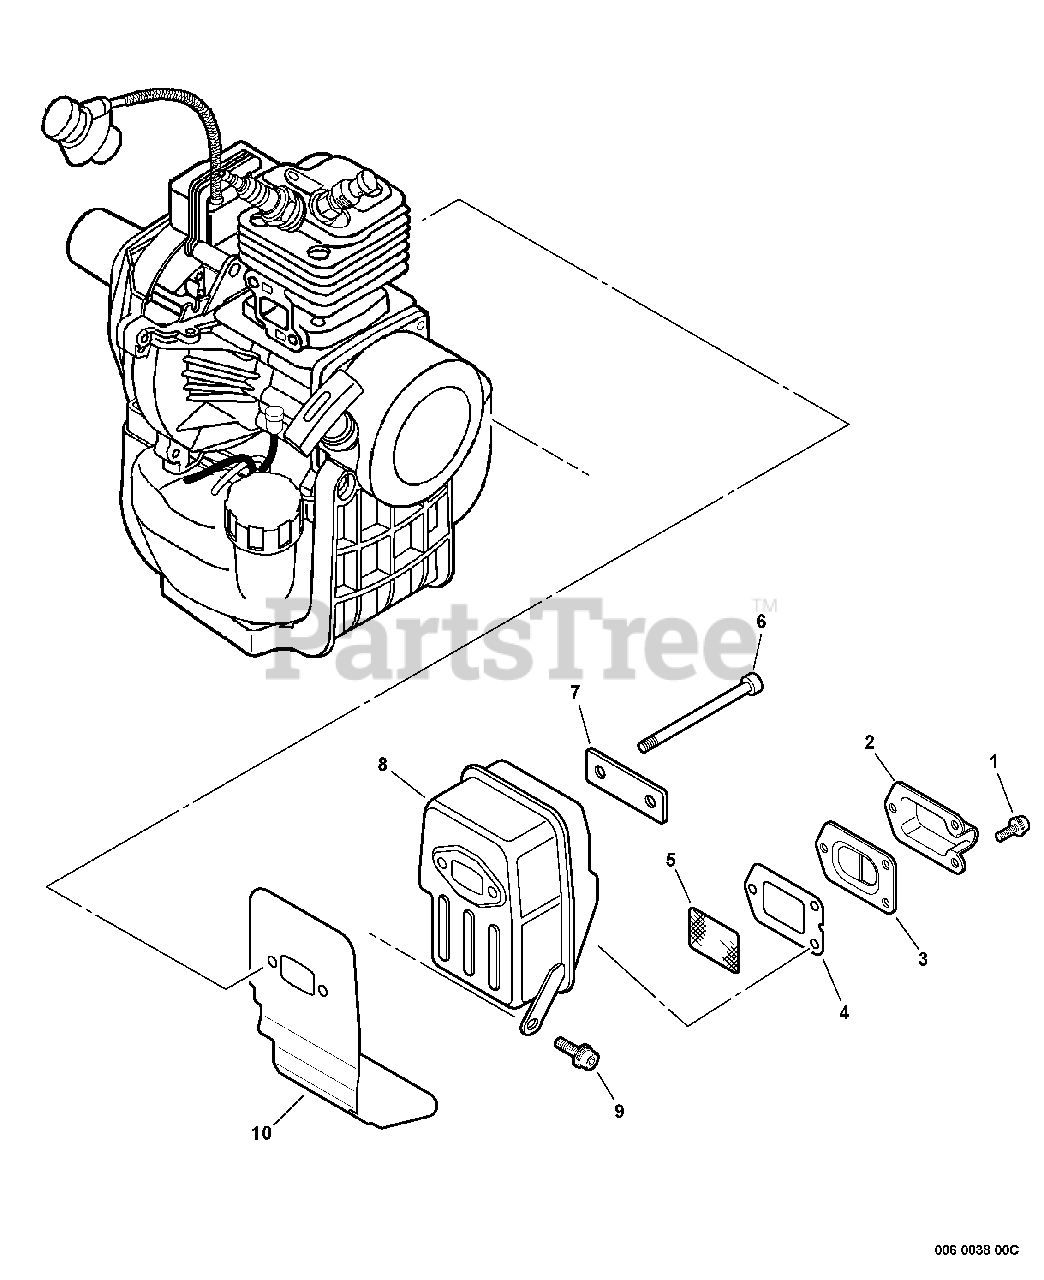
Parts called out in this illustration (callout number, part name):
1	SCREW - 4X10
2	GUIDE, EXHAUST - OUTER
3	GUIDE, EXHAUST - INNER
4	GASKET, EXHAUST
5	SCREEN, SPARK ARRESTOR
6	SCREW - 6X60
8	MUFFLER
9	SCREW - 5X12
10	SHIELD, EXHAUST
